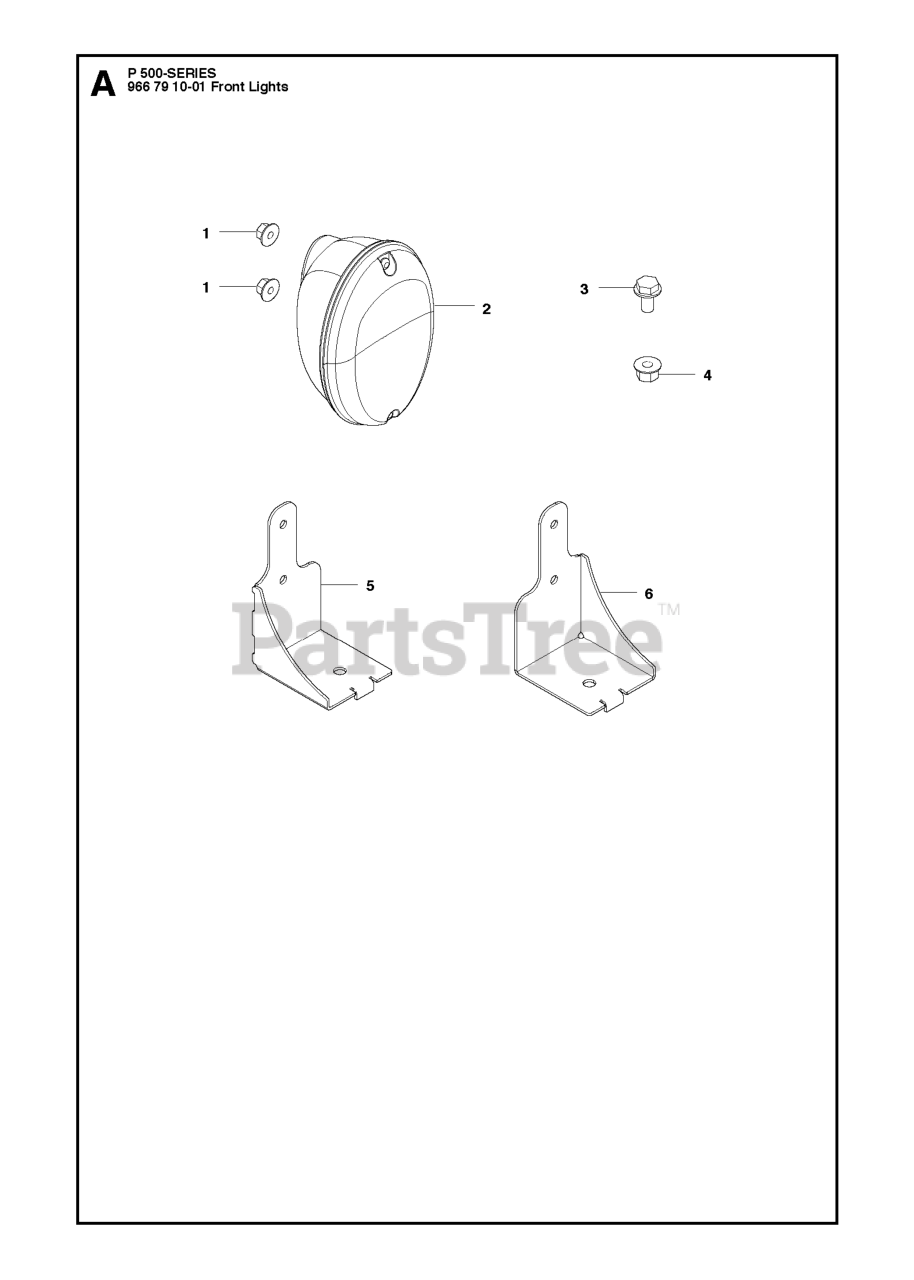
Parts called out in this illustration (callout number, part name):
1	NUT FLANGE
3	BOLT
4	NUT FLANGE
